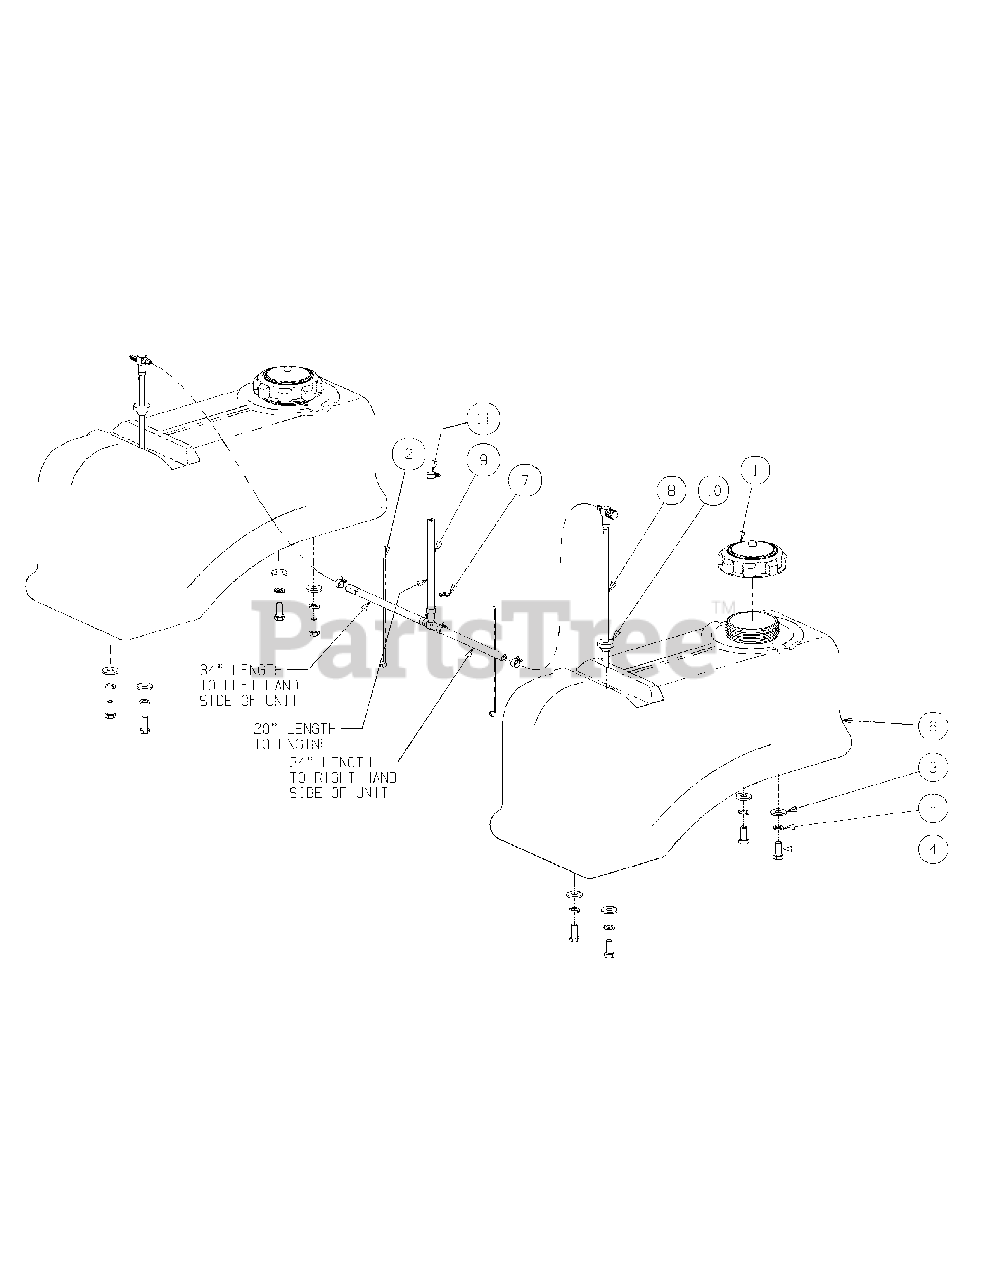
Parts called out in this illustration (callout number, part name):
1	Fuel Cap, 3.5, Tethered
2	Cable Tie
3	Flat Washer, .406 ID, 1.0 OD, .105
4	Hex, Cap Screw, 3/8-16, .88
5	Lock Washer, 3/8
6	Fuel Tank
7	Flat Washer, 1.4 x .630 x .0515
8	Fuel Fitting
9	Fuel Hose Assembly includes:
9	Hose, 1/4" Fuel Line (88 inches)
9	Clamp, Union
9	Tee Fitting, Fuel
10	Grommet, Fuel Tank
11	Hose Clamp, SAE #4: 1/4-5/8, SS
